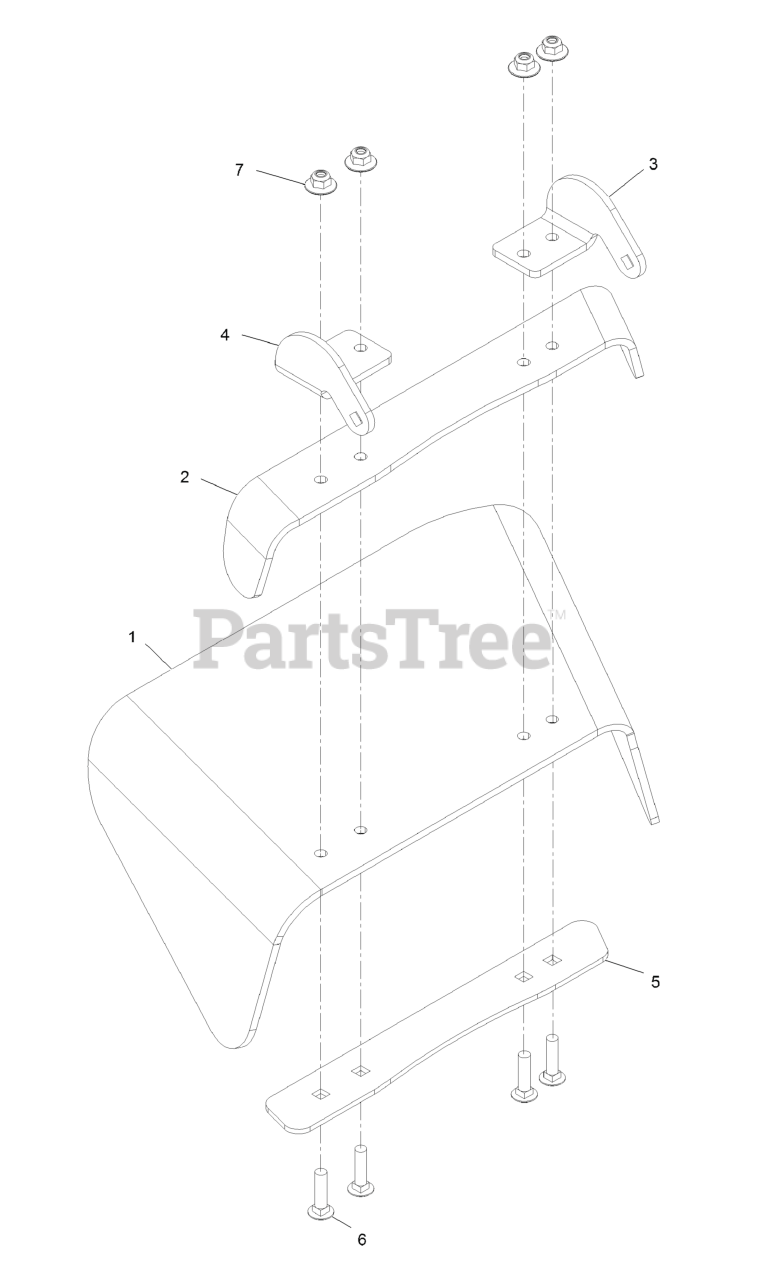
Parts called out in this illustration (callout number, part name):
1	DEFLECTOR-RUBBER
2	BRACKET-TOP DEFLECTOR
3	BRACKET-DEFLECTOR
4	BRACKET-DEFLECTOR
5	STRAP-BOTTOM DEFLECTOR
6	SCREW-CARR
7	Nut-Nyloc 3/8-16 Flg
